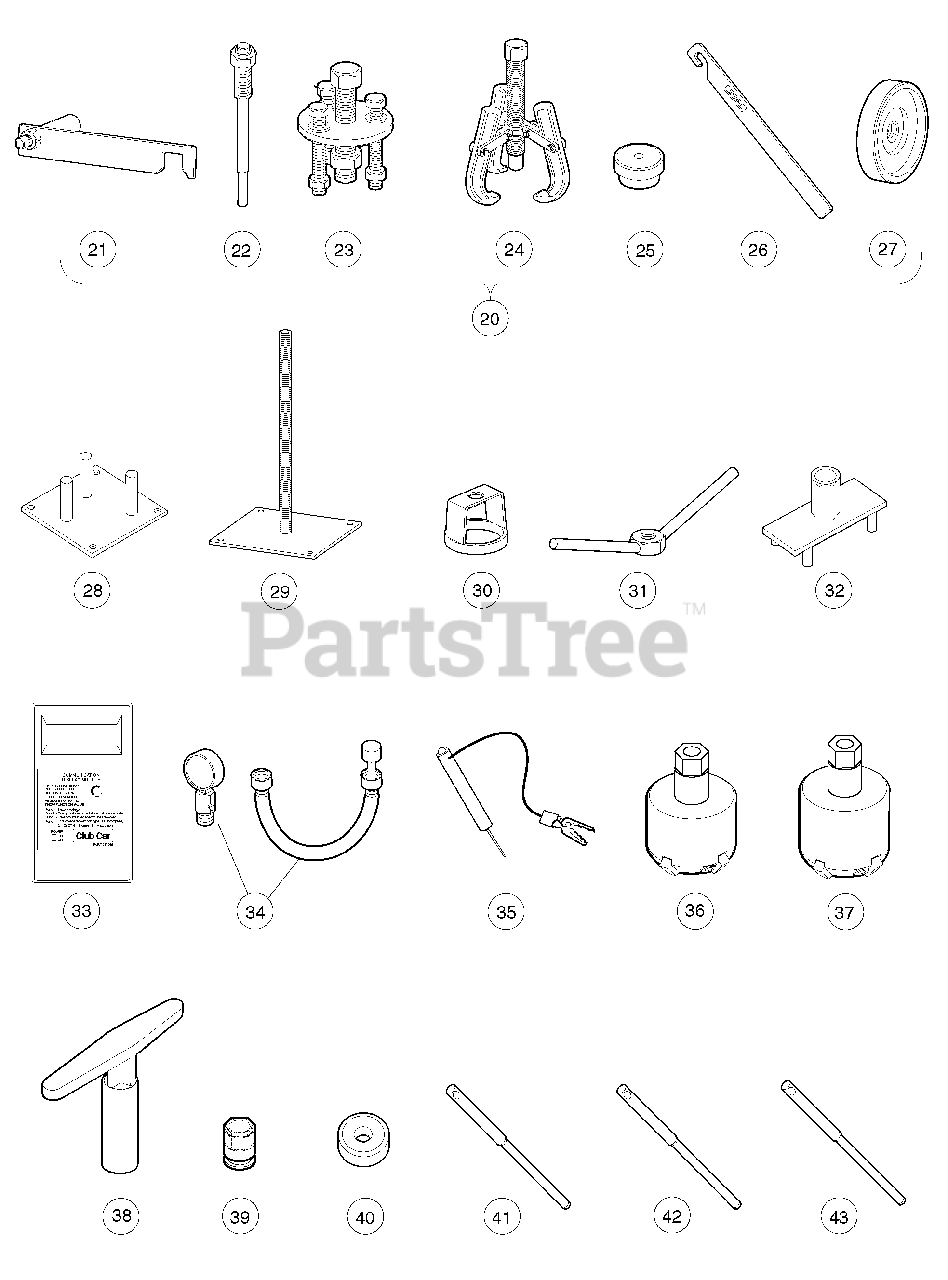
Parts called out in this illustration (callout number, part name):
20	Clutch Tool Kit
21	Clutch Alignment Tool
22	Drive Clutch Puller
23	Drive Clutch Hub Puller
24	Driven Clutch Cam Puller
25	Driven Clutch Puller Plug
26	Drive Clutch Holder Tool Assembly
27	Press Weldment
28	Drive ClutchFixed Sheave Tool
29	Driven Clutch Spring Compression Base
30	Driven Clutch Spring Compression Collar
31	Driven Clutch Spring Compression Nut
32	Drive Clutch Spider Removal Tool
33	Communication Display Module
34	Compression Gauge and Adapter
35	Continuity Tester
36	Cutter, Valve Seat, #122
37	Cutter, Valve Seat #115
38	Wrench, T, #505
39	Adapter, T-Wrench
40	Cutter, Valve Seat, 60 Degree
41	Pilot, 6.6 MM
42	Pilot, 6.62 MM
43	Pilot, 6.65 MM
